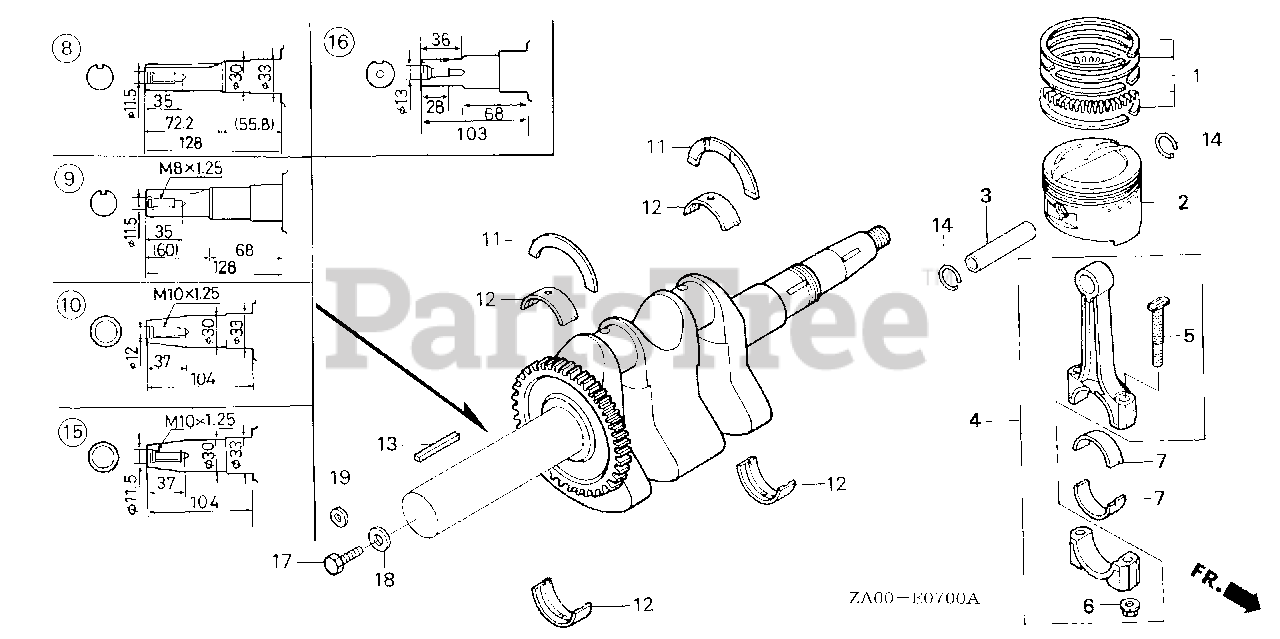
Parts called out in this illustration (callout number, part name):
1	RING SET, PISTON (STD)
1	RING SET, PISTON (OS 0.25)
1	RING SET, PISTON (0.25) (TEIKOKU)
1	RING SET, PISTON (0.50) (RIKEN)
1	RING SET, PISTON (OS 0.50)
2	PISTON (STD)
2	PISTON (OS 0.25)
2	PISTON (OS 0.50)
3	PIN, PISTON
4	ROD ASSY., CONNECTING
5	BOLT, CONNECTING ROD
6	NUT, CONNECTING ROD
7	BEARING A, CONNECTING ROD (Honda Code 0282053). (BLACK)
7	BEARING B, CONNECTING ROD (Honda Code 0282251). (BROWN)
7	BEARING C, CONNECTING ROD (Honda Code 0282285). (GREEN)
7	BEARING D, CONNECTING ROD (Honda Code 0282293). (YELLOW)
7	BEARING E, CONNECTING ROD (Honda Code 0282301). (RED)
8	CRANKSHAFT (D-TYPE)
11	BEARING, CRANKSHAFT THRUST
12	BEARING, CRANKSHAFT (1) (Honda Code 1278183). (BLACK)
12	BEARING, CRANKSHAFT (2) (Honda Code 1278191). (BROWN)
12	BEARING, CRANKSHAFT (3) (Honda Code 1278217). (GREEN)
12	BEARING, CRANKSHAFT (4) (Honda Code 1278225). (YELLOW)
12	BEARING, CRANKSHAFT (5) (RED)
13	KEY (6.3X6.3X43)
14	CLIP, PISTON PIN (14MM)
